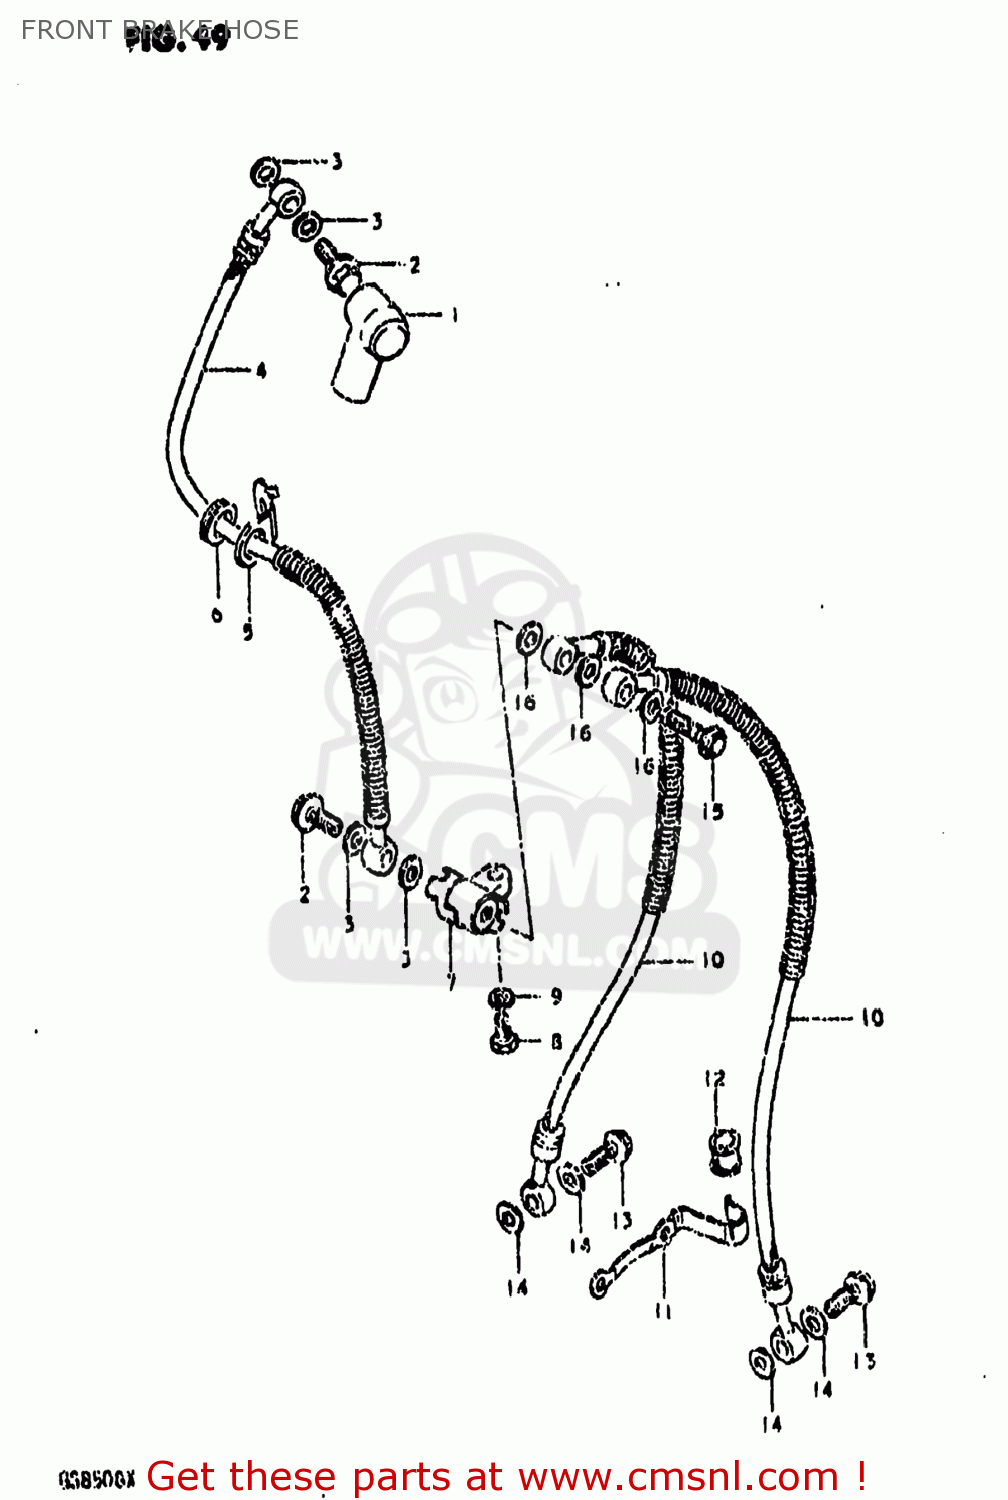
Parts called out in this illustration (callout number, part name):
1	BOOT,MASTER CYLINDER
2	BOLT,UNION
3	WASHER
4	HOSE,FRONT BRAKE
5	GUIDE,BRAKE HOSE
6	GROMMET
7	JOINT,BRAKE HOSE
8	BOLT
9	LOCK WASHER
10	HOSE,FRONT BRAKE
11	GUIDE,BRAKE HOSE NO.2
12	BUSH,BRAKE HOSE GUIDE,NO.2
13	BOLT,UNION
14	WASHER
15	BOLT,UNION
16	WASHER
